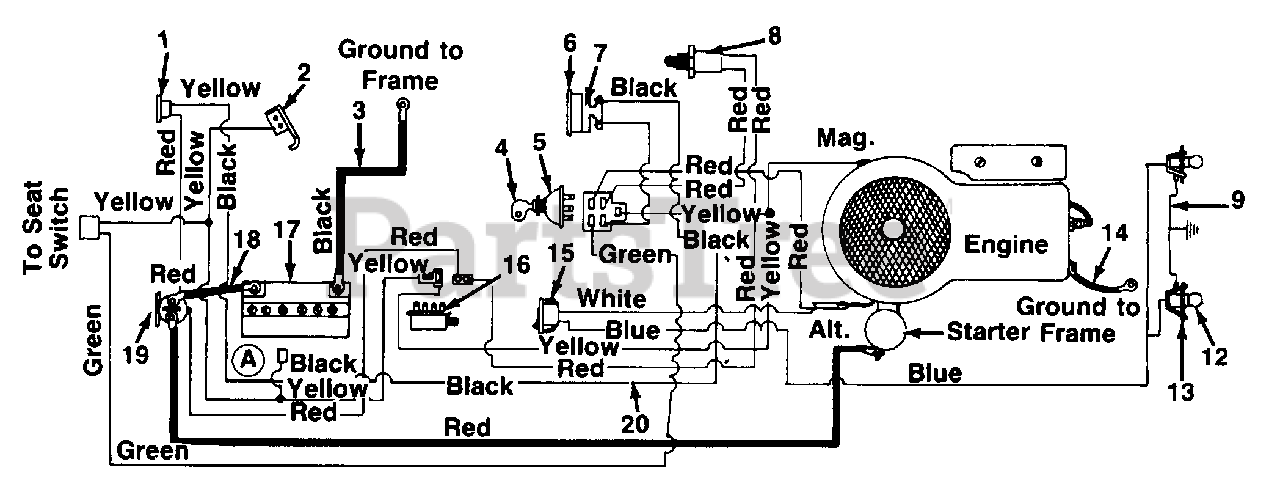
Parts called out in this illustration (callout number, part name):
1	Circuit Breaker
2	Spring-Switch-Reverse
3	Ground Wire 9.0" Lg.
4	Ignition Key
5	Ignition Switch
6	Ammeter
7	Foam Strip
8	Safety Switch
9	Ground Wire
12	Lamp
13	Socket
14	Ground Wire 7.25" Lg.
15	Light Switch
16	Safety Switch
17	Battery
18	Electric Wire w/Boot
19	Solenoid
20	Wire Harness
